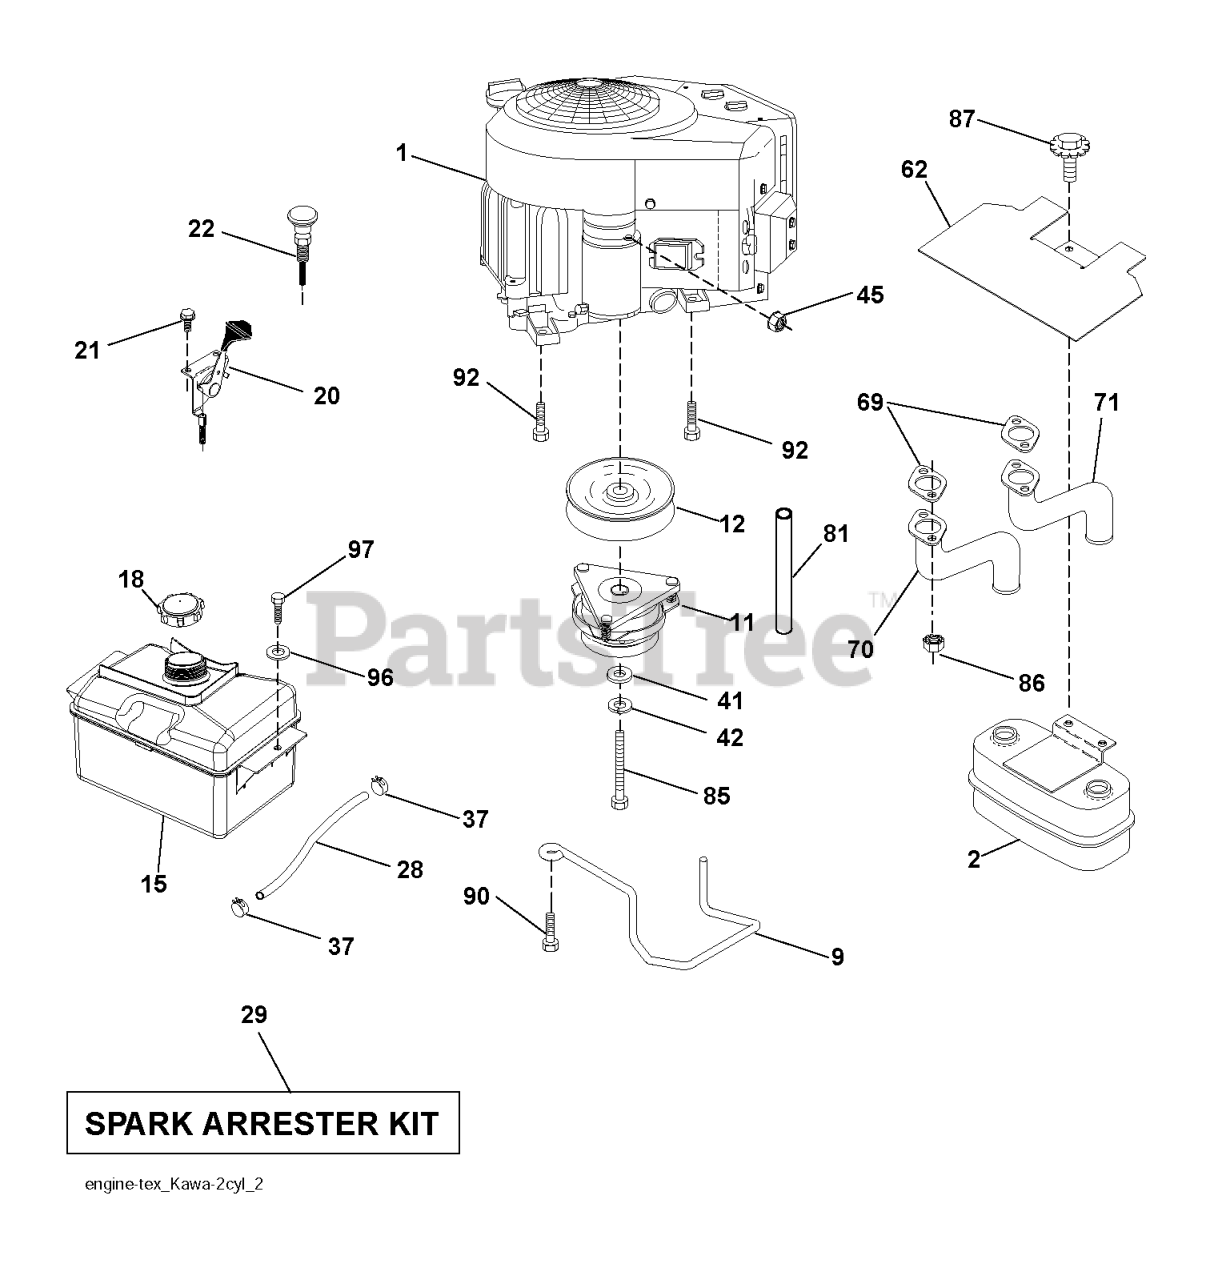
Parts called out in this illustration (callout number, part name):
2	MUFFLER.TWIN.CYL.LOW.TONE
9	KEEPER.BELT.ENGINE.4.2
11	RB.CLUTCH.OGURA.4.4.PD
12	PULLEY.ENGINE.TUFFTORQ
15	RP TANK FUEL FRT 1.5 GAL
18	CAP.FUEL.2.25"VENTED"
20	THROTTLE CABLE
21	SCREW.#10 X 0.750.BOS
22	CONTROL, CHOKE
28	LINE.FUEL.20
29	KIT.SPARK ARRESTOR 794945 B&S
37	HOSE CLAMP
42	LOCKWASHER
45	NUT
62	RP SHIELD HEAT MUFFLER
70	EXHAUST.TUBE.LH.KAWASAKI.
71	EXHAUST.TUBE.RH.KAWASAKI.
81	TUBE, DRAIN OIL ASM.
85	BOLT HEX 7/16-20X4-1/4"
86	NUT.HEX.FLANGE.TOPLOCK
87	BOLT.5/16-18UNCX3/4 W/SEMS.BLK
90	SCREW 3/8-16X1
92	SCREW 3/8-16X1
97	SCREW HEXWSHR 1/4-20X3/4
